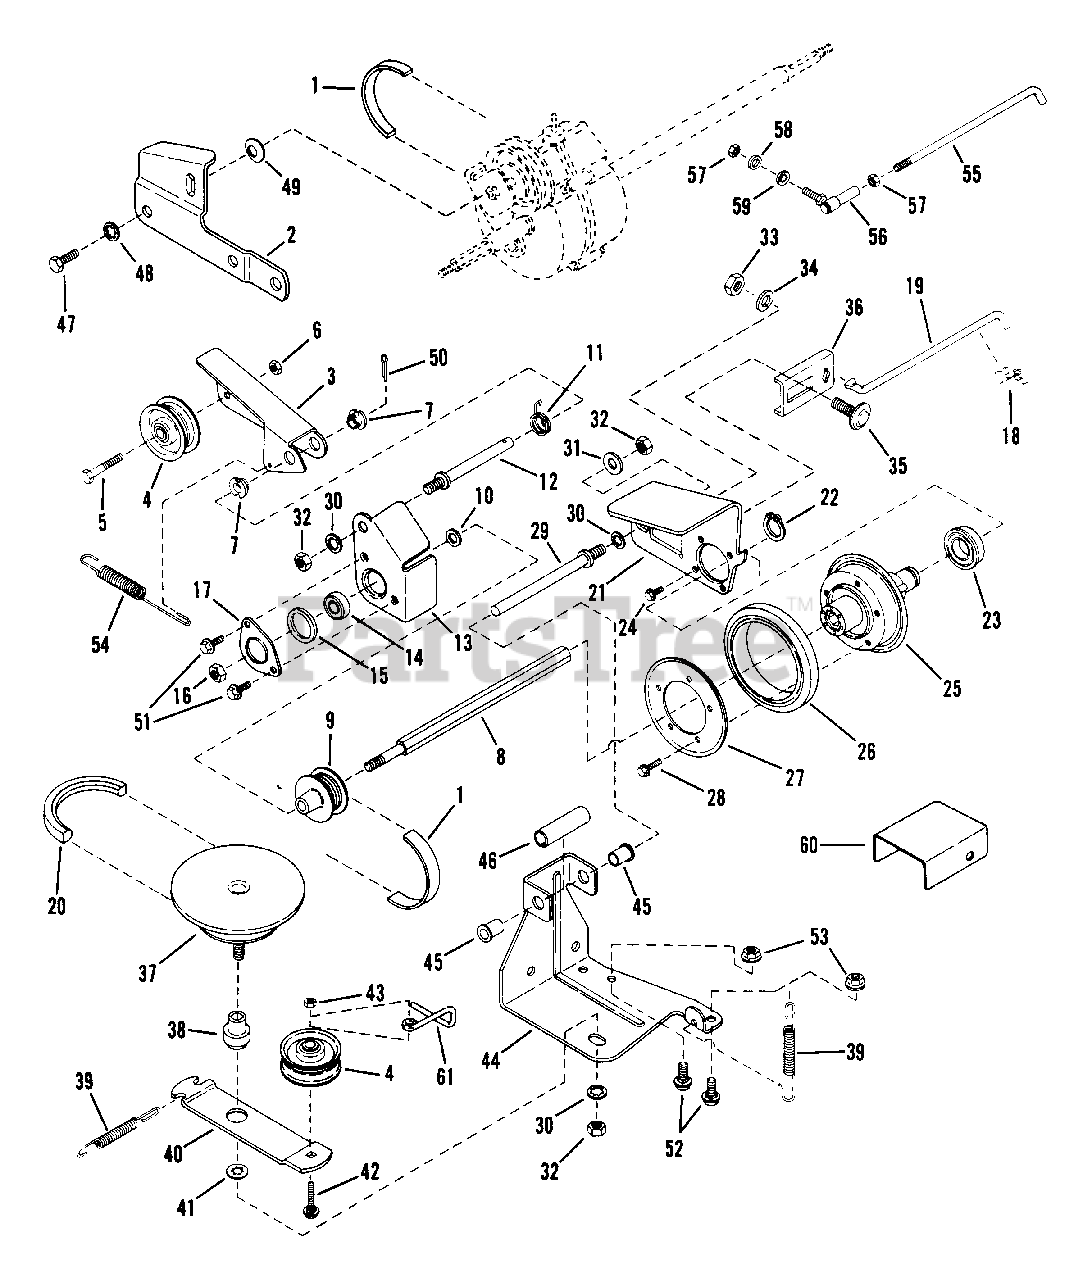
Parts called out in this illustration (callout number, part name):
1	BELT, Poly-Vee
2	LINK, Differential
3	ARM, Clutch Idler
4	PULLEY, Idler
5	SCREW, 1/4-28 x 1-3/8" Hex Head Cap
6	NUT, 1/4-28 Hex Lock
7	BUSHING, 3/8 I.D. Nylon
8	SHAFT, Hex
9	PULLEY, Poly-V
10	WASHER, 3/8" Flat
11	SPRING, Torsion
12	STUD
13	HOLDER, Bearing (Inner Half)
14	BEARING, Ball
15	O-RING
16	NUT, 3/8-24 Hex Center Lock
17	HOLDER, Bearing (Outer Half)
18	CLIP, 1/4 Right Arc (Transfer Rod)
19	ROD, Transfer
20	BELT, Engine Drive
21	PLATE, Thrust
22	RING, Retaining
23	BEARING, Ball
24	SCREW, #10-32 x 1/4" Self-Tapping Machine
25	ASSEMBLY, Hub
26	RING, Driven
27	PLATE, Ring Retaining
28	SCREW, #10-24 x 1/2" Hex Washer Self-Tap (Torx)
29	GUIDE, Thrust Plate
30	WASHER, 3/8 Internal Tooth Lock
31	WASHER, 3/8" Flat
32	NUT, 3/8-24 Hex
33	NUT, 5/16-18 Hex
34	WASHER, 5/16 Split Lock
35	BOLT, 5/16-18 x 3/4" Carriage
36	CONNECTOR, Transfer Rod
37	ASSEMBLY, Drive Disc
38	BUSHING
39	SPRING (Wheel Drive & Idler)
40	ARM, Idler
41	RETAINER, 3/8 Bolt
42	BOLT, 1/4-20 x 1-1/2" Carriage
43	NUT, 1/4-20 Hex Center Lock
44	BRACKET, Deck
45	BUSHING, Flange
46	SPACER
47	SCREW, 5/16-18 x 1/2" Hex Head Cap
48	WASHER, 5/16 Internal Tooth lock
49	WASHER, Spring
50	PIN, 3/32 x 1/2" Cotter
51	SCREW, 1/4-20 x 1/2" Self-Tapping
52	BOLT, 5/16-18 x 5/8" Short neck Carriage
53	NUT, 5/16-18 x 5/8" Hex Flange Nut
54	SPRING, Clutch
55	LINK, Transfer
56	JOINT, Ball
57	NUT, 1/4-28 Hex
58	WASHER, 1/4 Flat
59	WASHER, 1/4 Internal Tooth Lock
60	SHIELD, Hex Shaft
61	SCRAPER, Drive Pulley
